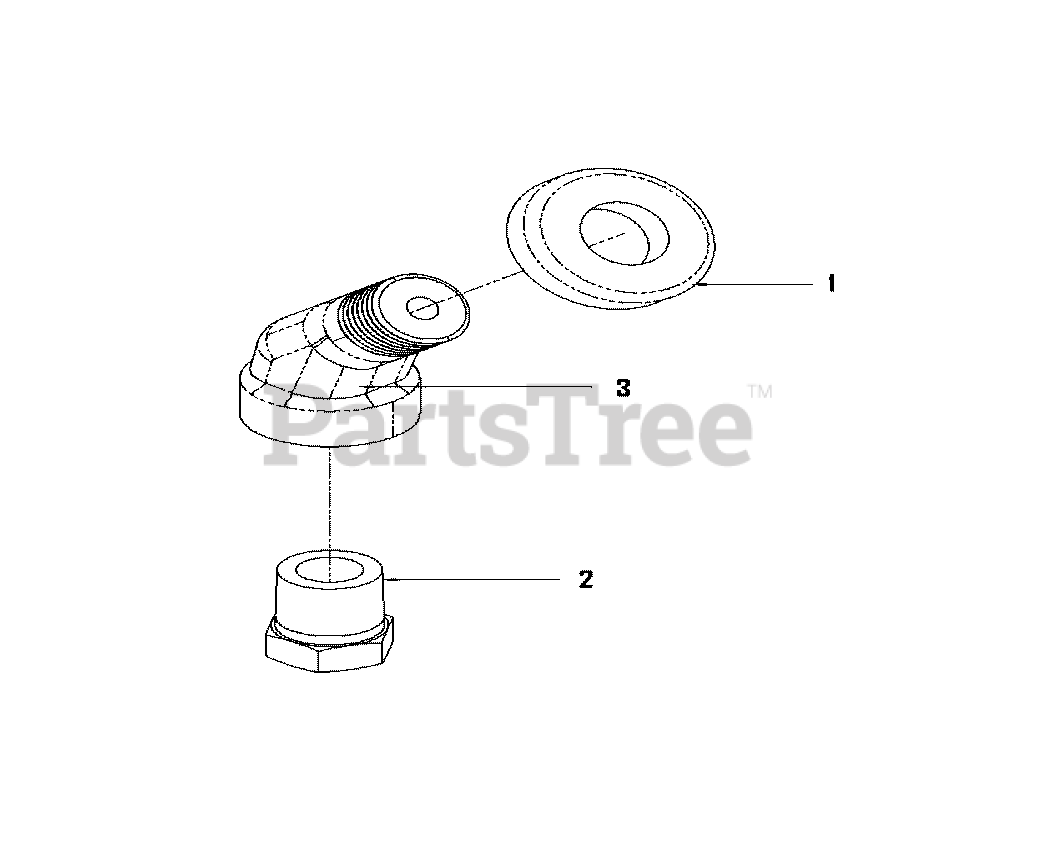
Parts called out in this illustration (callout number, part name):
1	* ADAPTER
2	* PLUG
3	* PIPE
